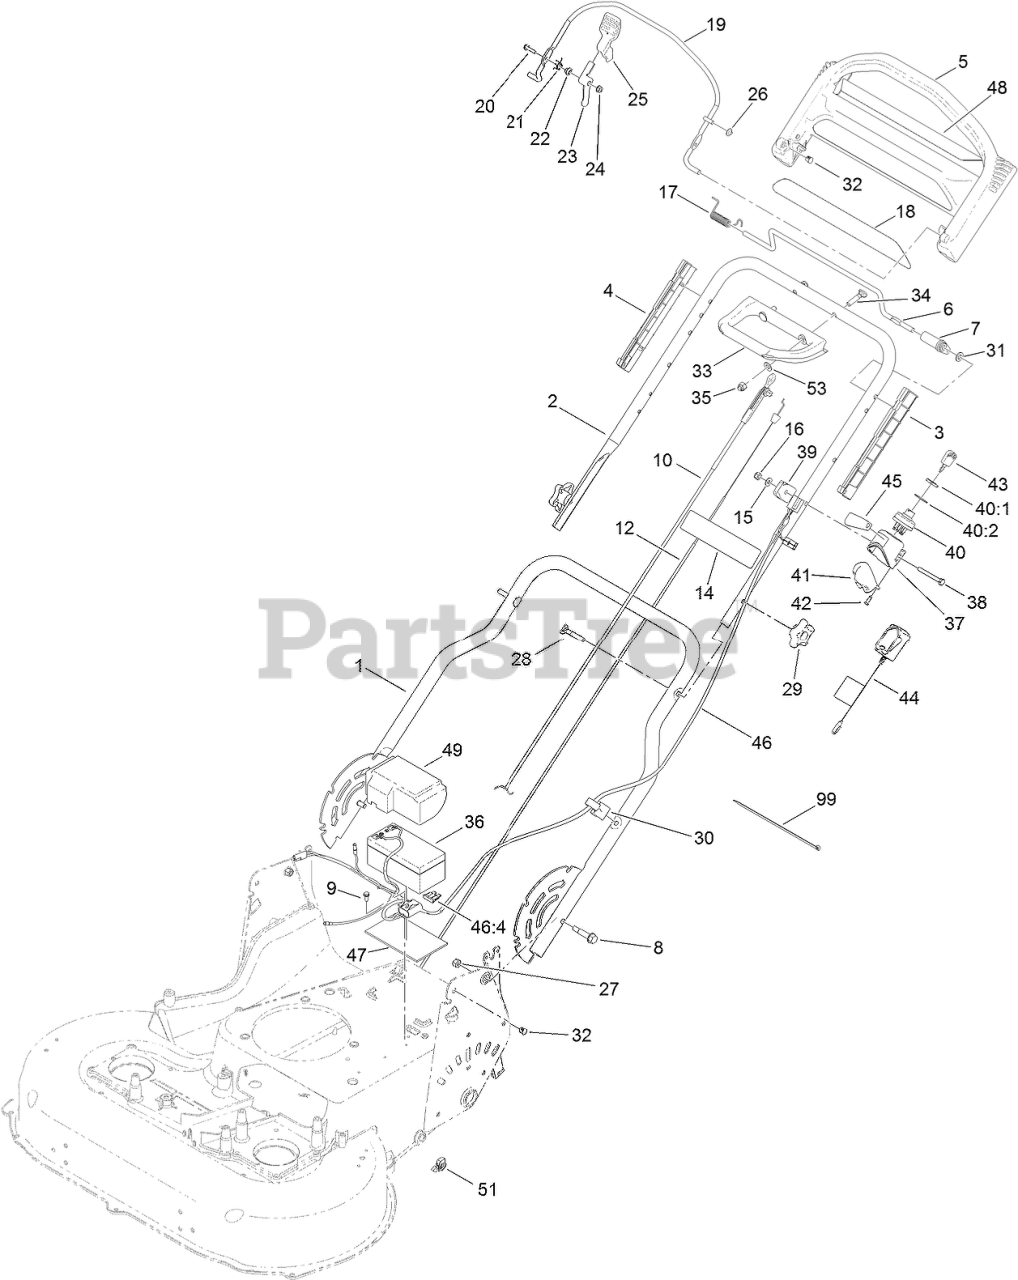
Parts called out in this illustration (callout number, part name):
1	HANDLE-LOWER
2	HANDLE-UPPER
3	GUIDE-LH
4	GUIDE-RH
5	HANDLE-CONTROL
6	BAR-CONTROL, TRACTION
7	LEVER-TRACTION
8	BOLT-SHOULDER, HHF
9	SCREW-TAPTITE
10	CABLE-BRAKE, BBC
12	CABLE-TRACTION
14	DECAL-WARNING
15	WASHER-FLAT
16	NUT-LOCK, NI
17	Spring-Torsion
19	BAIL-BRAKE
20	SCREW-HWH
21	SPRING-TORSION
22	SPACER
23	LEVER
24	NUT-LOCK, FLANGE
26	NUT-SPEED
27	NUT-LOCK, NI
28	SCREW-HANDLE
29	KNOB-HANDLE
30	GUIDE-CABLE
31	WASHER-PLAIN
32	Plug-Dome
33	HANDLE-ASSIST, TRACTION
34	SCREW-HANDLE
35	NUT-HEX, NYLON CAP
36	BATTERY-WET
37	HOUSING-SWITCH, KEY
38	SCREW-HH
39	ANCHOR-CABLE, UPPER
40	SWITCH-STARTER
40:1	NUT-HH
40:2	WASHER-TOOTH, INTERNAL
41	COVER-SWTCH
42	SCREW-PPH
44	CHARGER-BATTERY
45	DECAL-SWITCH, IGNITION
46	HARNESS-WIRE
46:4	FUSE-40 AMP
47	FOAM-BATTERY
48	DECAL-ASSIST, TRACTION
49	COVER-BATTERY
51	CLIP-CONDUIT
53	SPACER
99	TIE-CABLE
